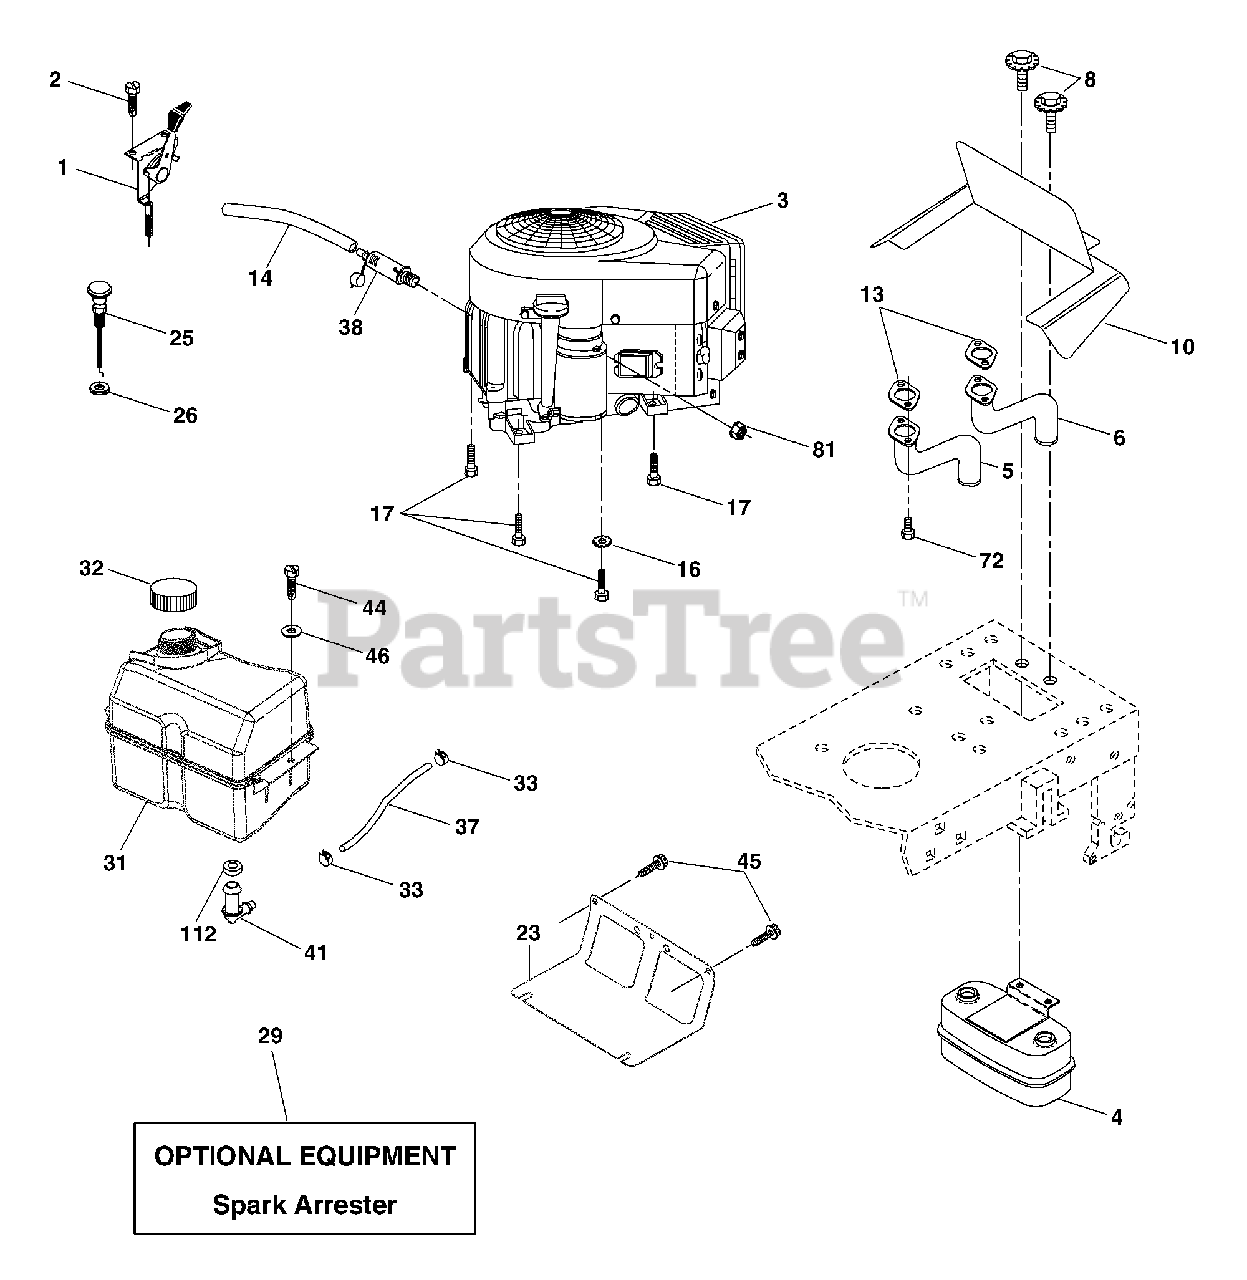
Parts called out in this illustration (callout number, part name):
1	Control Th/ch Flag
2	Screw Hex Thd Cut 1/4-20x5/8 T
4	Muffler Exhaust
5	Exhaust Tube LH
6	Exhaust Tube RH
8	Bolt 5/16-18 UNC x 3/4
10	Shield Browning
11	Washer Lock 5/16
12	Screw Hex 5/16-18 x 3/4
13	Gasket Muffler
14	Tube Drain Oil Easy
16	Washer Lock Ext Tooth 3/8
17	Screw 3/8-16 x 1-1/2
23	Shield Brn/Dbr Guard
25	Control Choke
26	Nut Keps 3/8-24 Unf
29	Arrestor Spark
31	Tank Fuel Front 2 00
32	Cap Fuel
33	Clamp Hose Black
37	Line Fuel 20"
38	Plug Oil Drain
41	Stem Tank Fuel
44	Screw Hex wsh Thdrol 1/4-20x3/4
45	Screw Hex Wsh Thdrol 3/8-16 x 3/4
46	Washer 9/32 X 7/8 X 16 Ga
72	Screw Socket Head 5/16-18 x 1
81	Nut Keps Hex 1/4-20 Unc
112	Bushing
